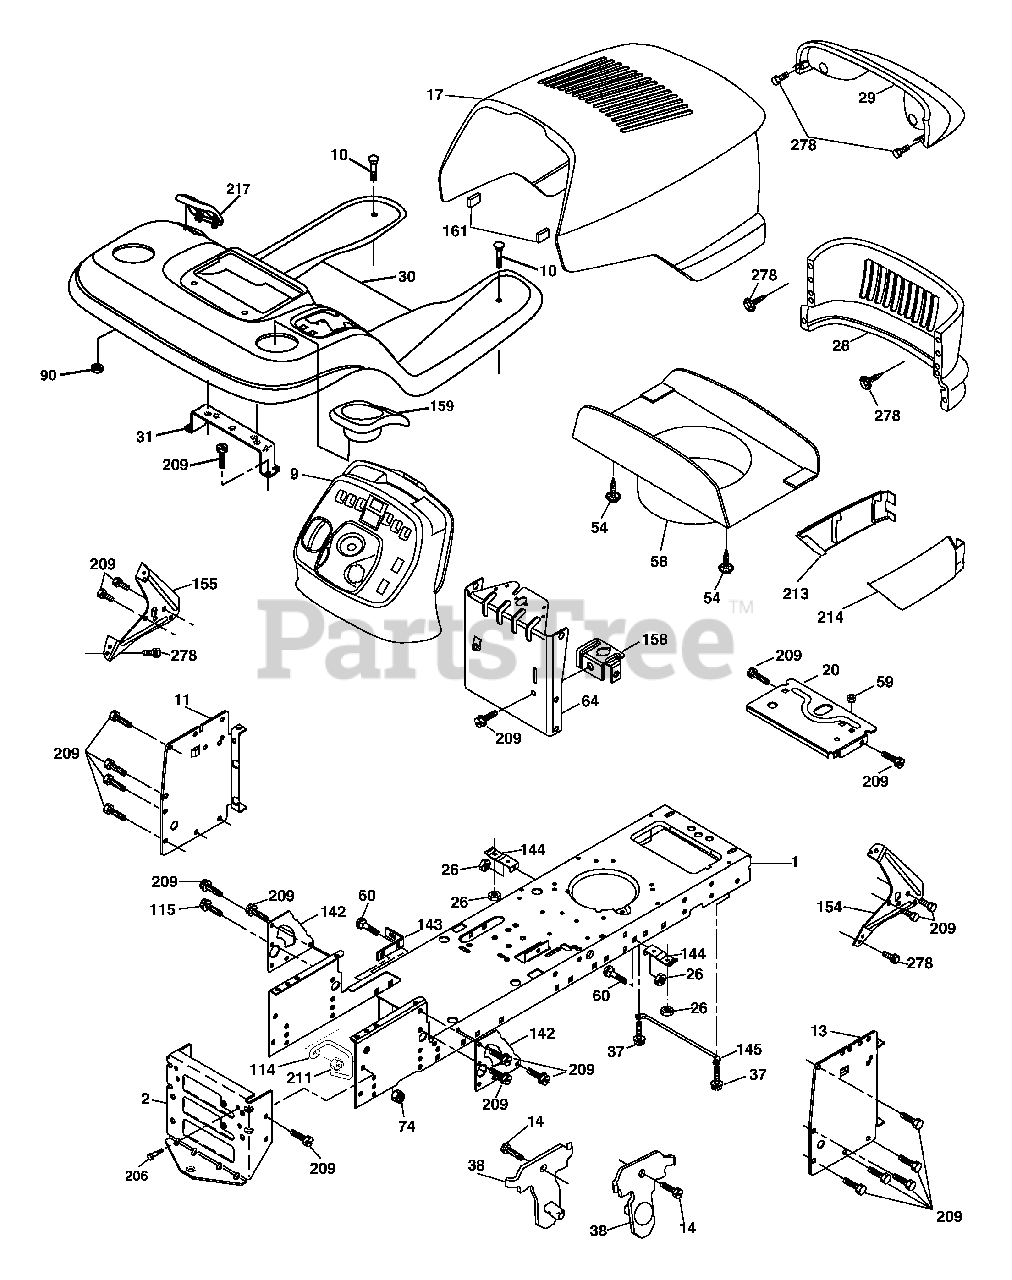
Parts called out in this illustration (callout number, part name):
1	Chassis
2	Drawbar
9	Dash P/L
10	Bolt Carriage 3/8-16 x 1
11	Panel Dash Lh
13	Panel Dash Rh
14	Screw Thdrol 3/8-16 x 1/2
17	Hood
20	Plate Battery
26	Nut Lock Hex W/Ins 3/8-16 unc
28	Grille
29	Lens Bar
31	Bracket Fender
37	Screw Thdrol 6/16-18 x 1/2 TYT
38	Bracket Asm Pivot Mower Rear
54	Screw WSHD Hex 10-32 x 5/8
58	Duct Air
59	Bushing 1.375 OD
60	Bolt RDHD SQNK 3/8-16 UNC x 3/4
64	Dash Lower STLT
74	Nut Crownlock 3/8-16 UNC
90	Nut Self-Thd Wsh-Hd 1/4
114	Keeper Belt Rear LH
115	Screw 3/8-16 x 1-1/4
142	Plate Reinforcement STLT
143	Bracket Swaybar Chassis
144	Bracket Footrest Step-Thru
145	Rod Pivot Chassis/Hood
154	Bracket Dash RH
155	Bracket Dash LH
158	Bracket Parking Brake
159	Cupholder
161	Bumper Hood
206	Bolt Shoulder 5/16-18
209	Screw Hexwsh Thdr 3/8-16 x 3/4
211	Nut Hex Flange Lock
213	Skirt Grille LH
214	Skirt Grille RH
217	Console Fuel Window
278	Screw 10 x 3/4 Single Lead-Hex
